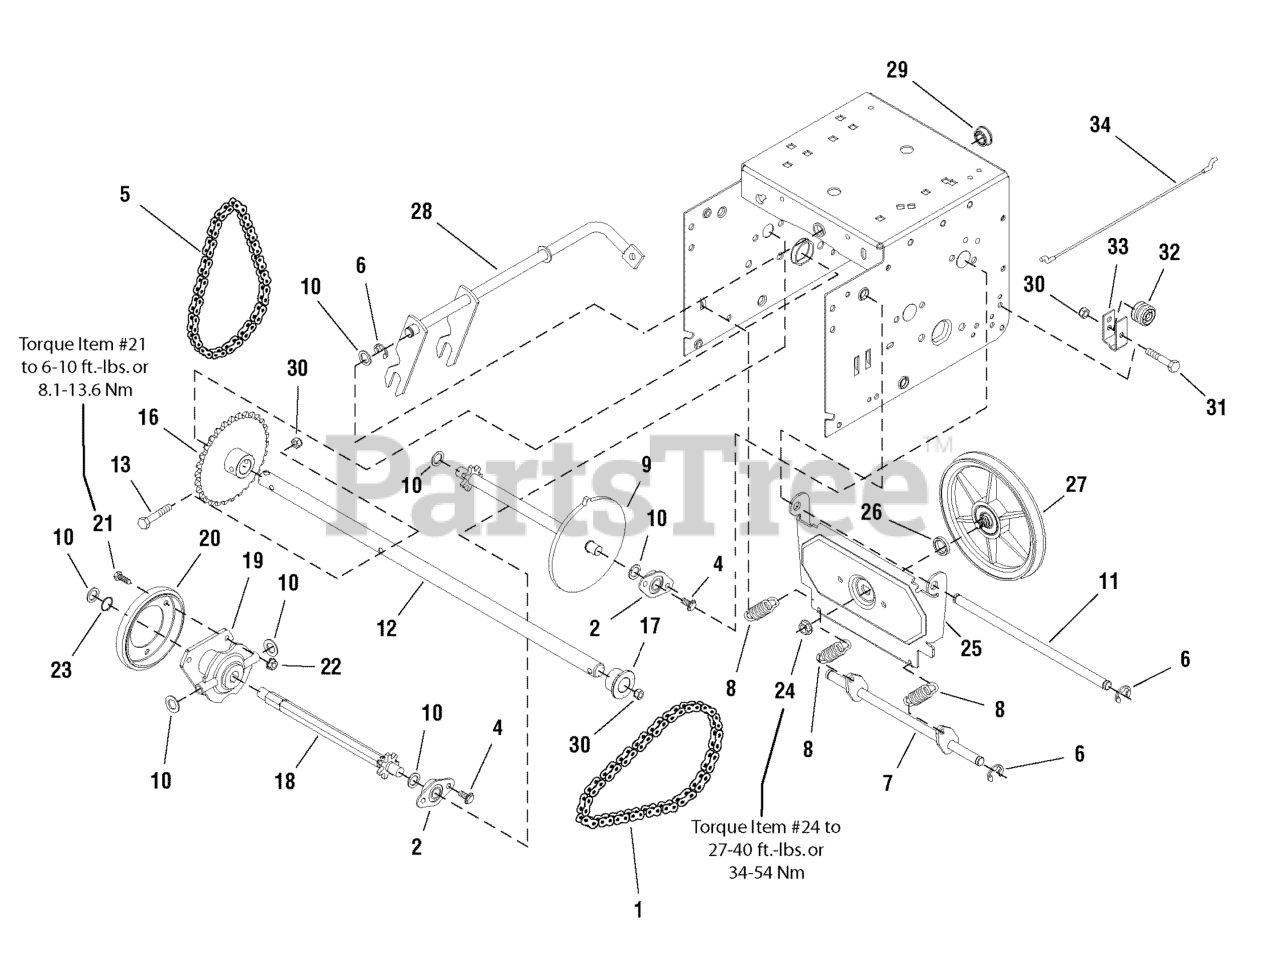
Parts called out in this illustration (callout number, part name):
1	CHAIN, Roller
2	RETAINER & BUSHING ASSEMBLY
4	SCREW, Hex Washer Head Taptite, 5/16-18 x 1/2
5	CHAIN, Roller
6	RETAINER, Ring 7/16
7	SPRING LINK ASSEMBLY
8	SPRING, Extension
9	SPROCKET, Set
10	WASHER, 1/2
11	AXLE, Swing Plate
12	AXLE, Bushing
13	BOLT, Hex 1/4-20 x 1-3/4 G8
16	SPROCKET, Axle
17	BEARING, Axle D-Hole
18	HEX SHAFT & SPROCKET ASSEMBLY
19	HUB, Friction Wheel & Bearing
20	WHEEL, Friction
21	CAPSCREW, Hex Head 1/4-20 x 5/8 G5
22	NUT, Hex KEPS 1/4-20
23	RING, Retaining Extension
24	NUT, 3/8-24 Flange Lock
25	PLATE, Swinging
26	SPACER, Friction Pulley
27	FRICTION PULLEY ASSEMBLY
28	SPEED SELECT ASSEMBLY
29	BEARING, Flange
30	NUT, Hex Lock ESNA Light 1/4-20
31	CAPSCREW, Hex Head, 1/4-20 x 1-1/2 G5
32	SPOOL CABLE, Auger Control
33	BRACKET, Cable Spool
34	CABLE, Front Drive Lower All
